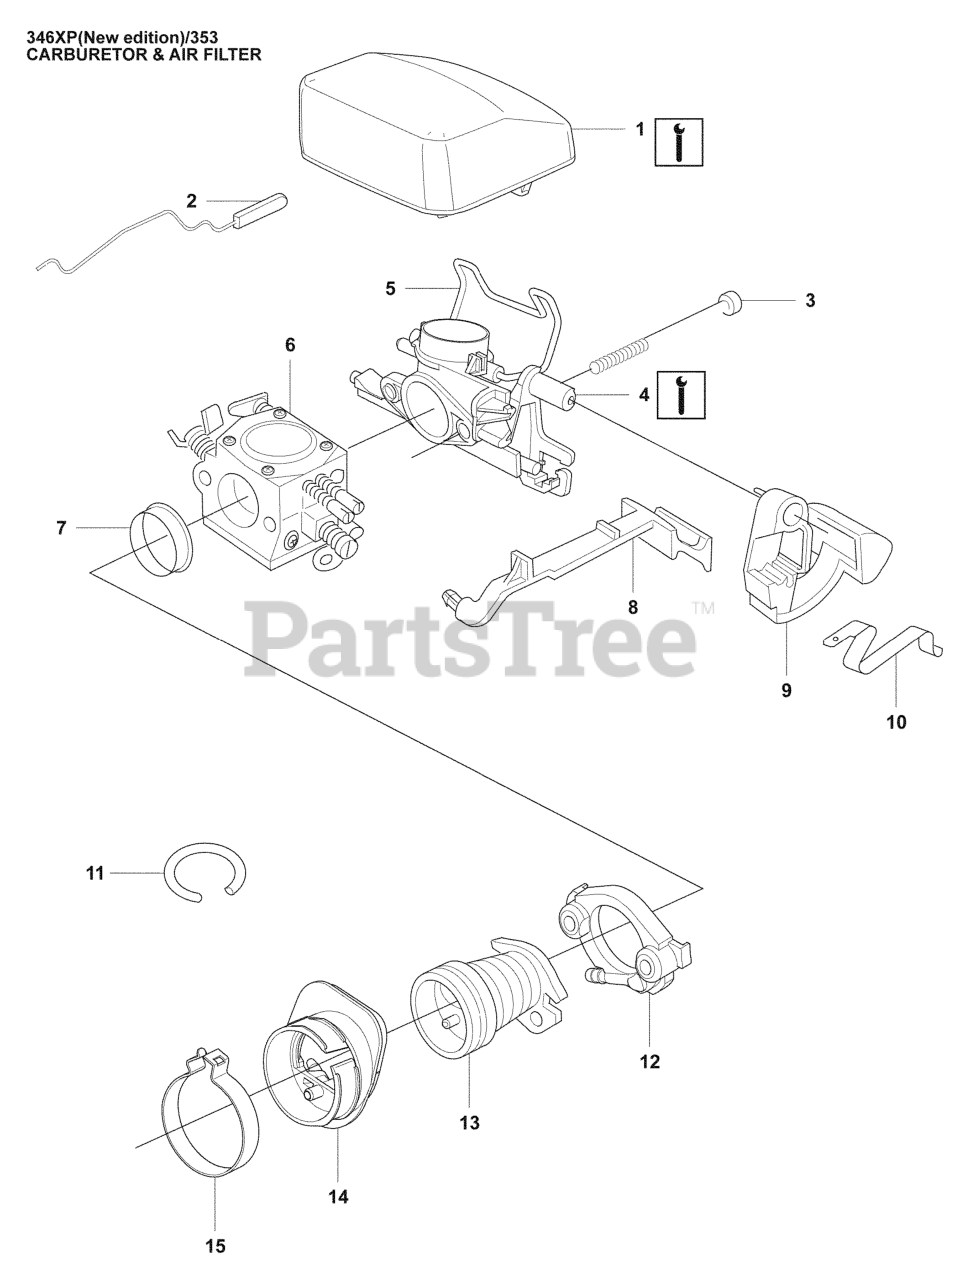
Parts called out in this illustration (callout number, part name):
1	AIR FILTER - NYLON (B)
1	AIR FILTER - NYLON (Y)
1	AIR FILTER - FELT
2	THROTTLE ROD
4	INLET ELBOW
5	FILTER CLAMP
6	CARBURETOR
7	RING
8	CHOKE CONTROL
11	HOSE, IMPULSE
12	FLANGE
15	CLAMP, INTAKE
